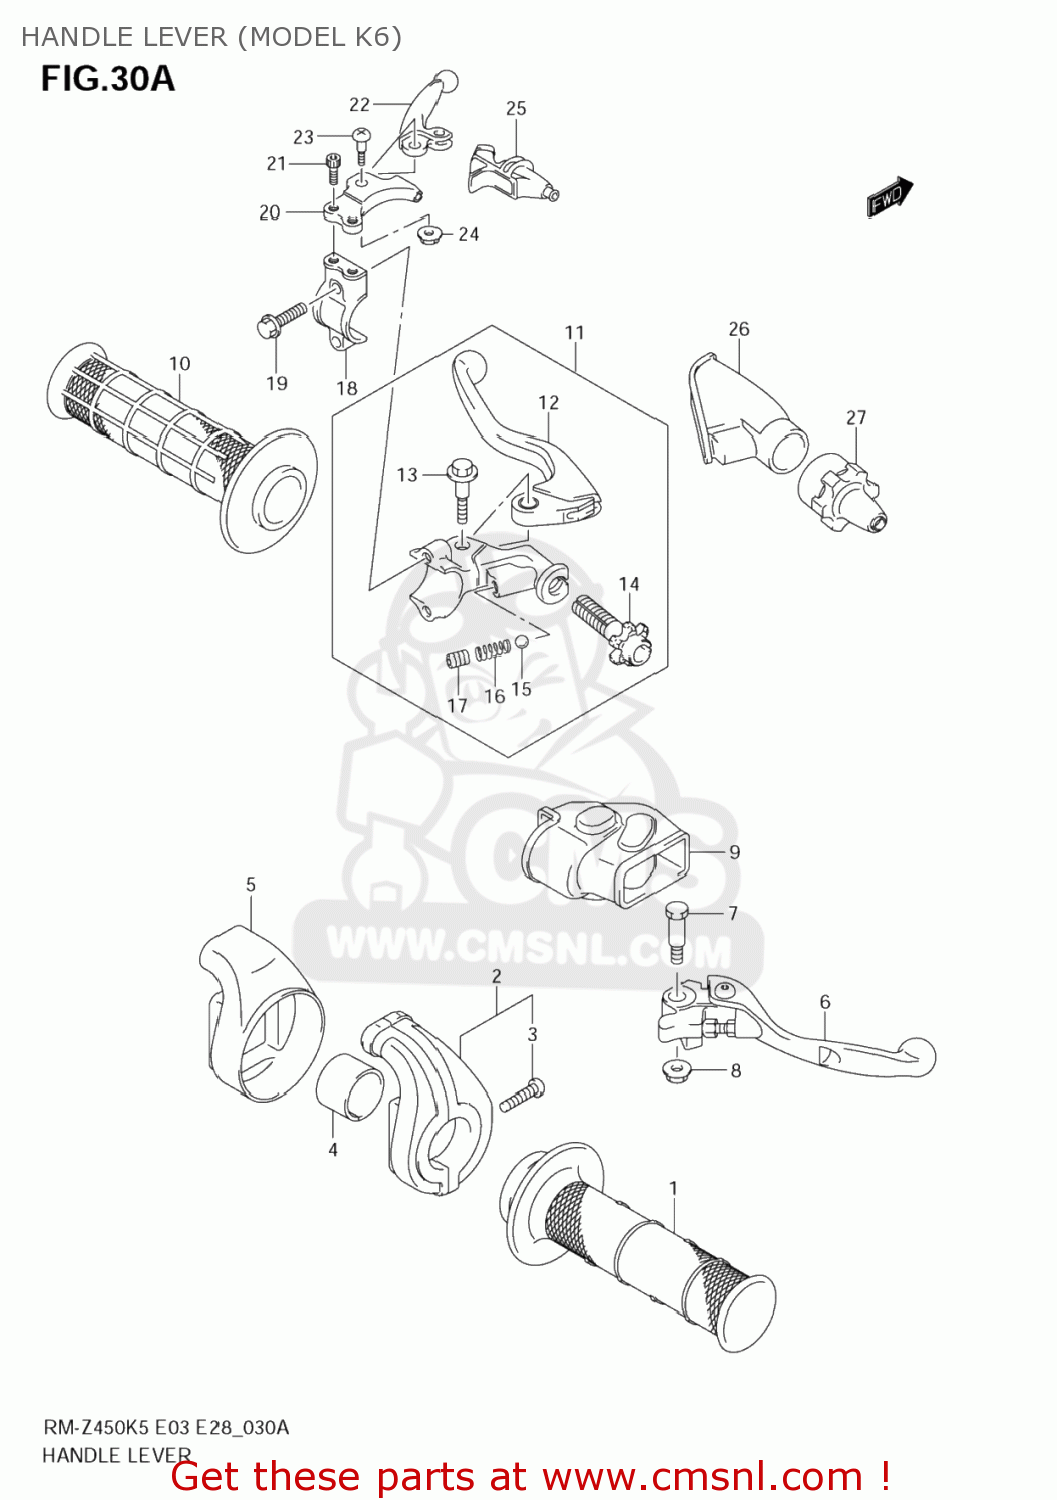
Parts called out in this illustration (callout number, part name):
1	GRIP,THROTTLE
2	CASE ASSY,THROTTLE
3	SCREW,CASE
4	COLLAR,THROTTLE CASE
5	COVER,THROTTLE CASE
6	LEVER ASSY,BRAKE
7	BOLT,BRAKE LEVER
8	NUT
9	COVER,BRAKE LEVER
10	GRIP,L
11	LEVER ASSY,CLUTCH
12	LEVER,CLUTCH
13	BOLT
14	ADJUSTER,CLUTCH CABLE
15	BALL
16	SPRING
17	SCREW(6X8)
18	HOLDER,CLUTCH LEVER
19	BOLT,BRACKET
20	HOLDER,HOT STARTER LEVER
21	SCREW(5X12)
22	LEVER,HOT STARTER
23	BOLT,HOT STARTER LEVER
24	NUT
25	COVER,HOT STARTER LEVER
26	COVER,CLUTCH LEVER
27	COVER,CLUTCH ADJUSTER
